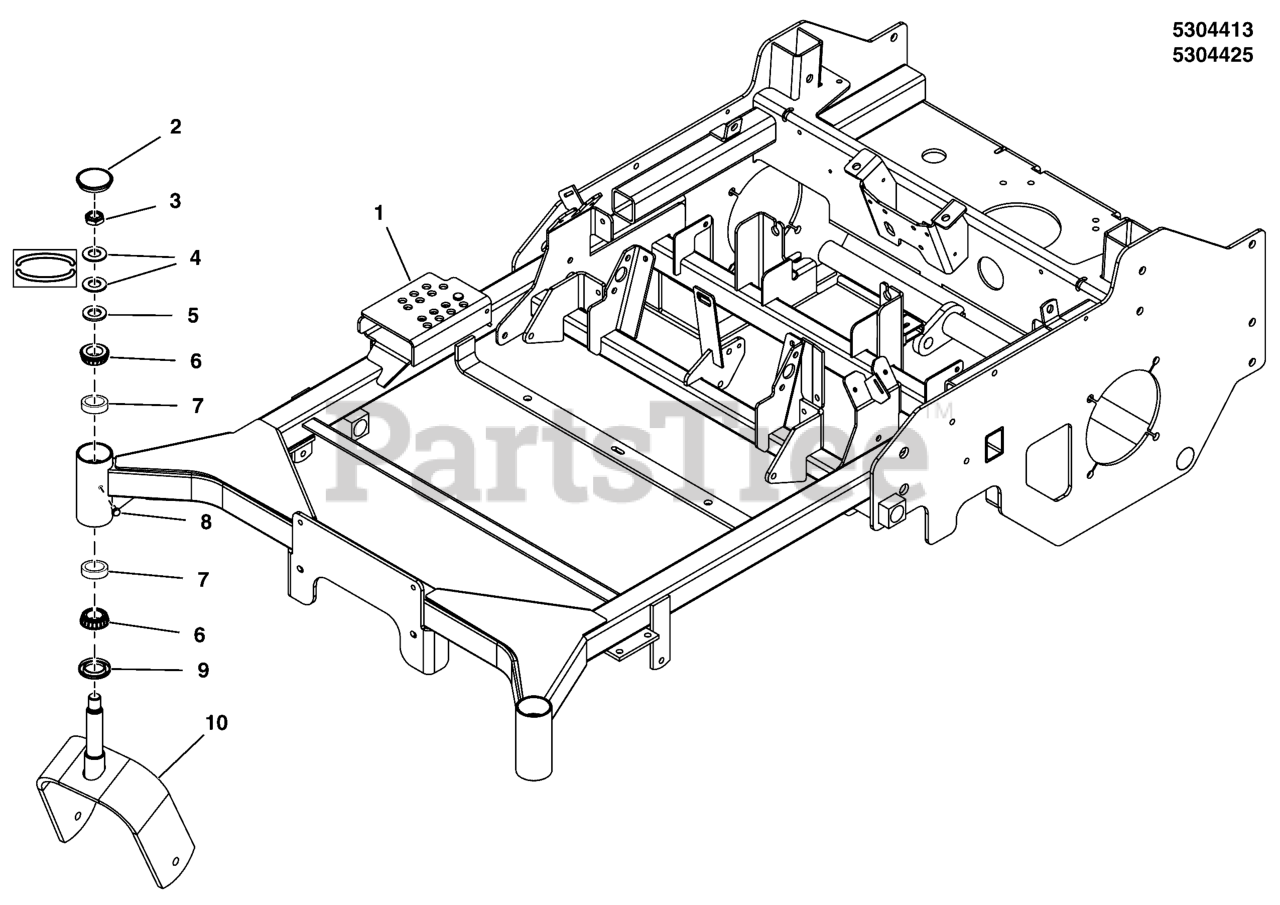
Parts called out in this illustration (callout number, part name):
1	WELD, MAIN FRAME, F320Z - RED
2	CAP, GREASE, LOW PROFILE
3	NUT, 3/4-16, HEX JAM NYLON LOCK
4	WASHER, BELLEVILLE - 1.500 X .755
5	WASHER, 3/4 SAE
6	BEARING, TAPERED ROLLER, 1"
7	CUP, BEARING (SV)
8	BOLT, 1/4-28 X 1/2, GD5 YZ
9	SEAL, GREASE
10	WELD, CASTER YOKE - RED
